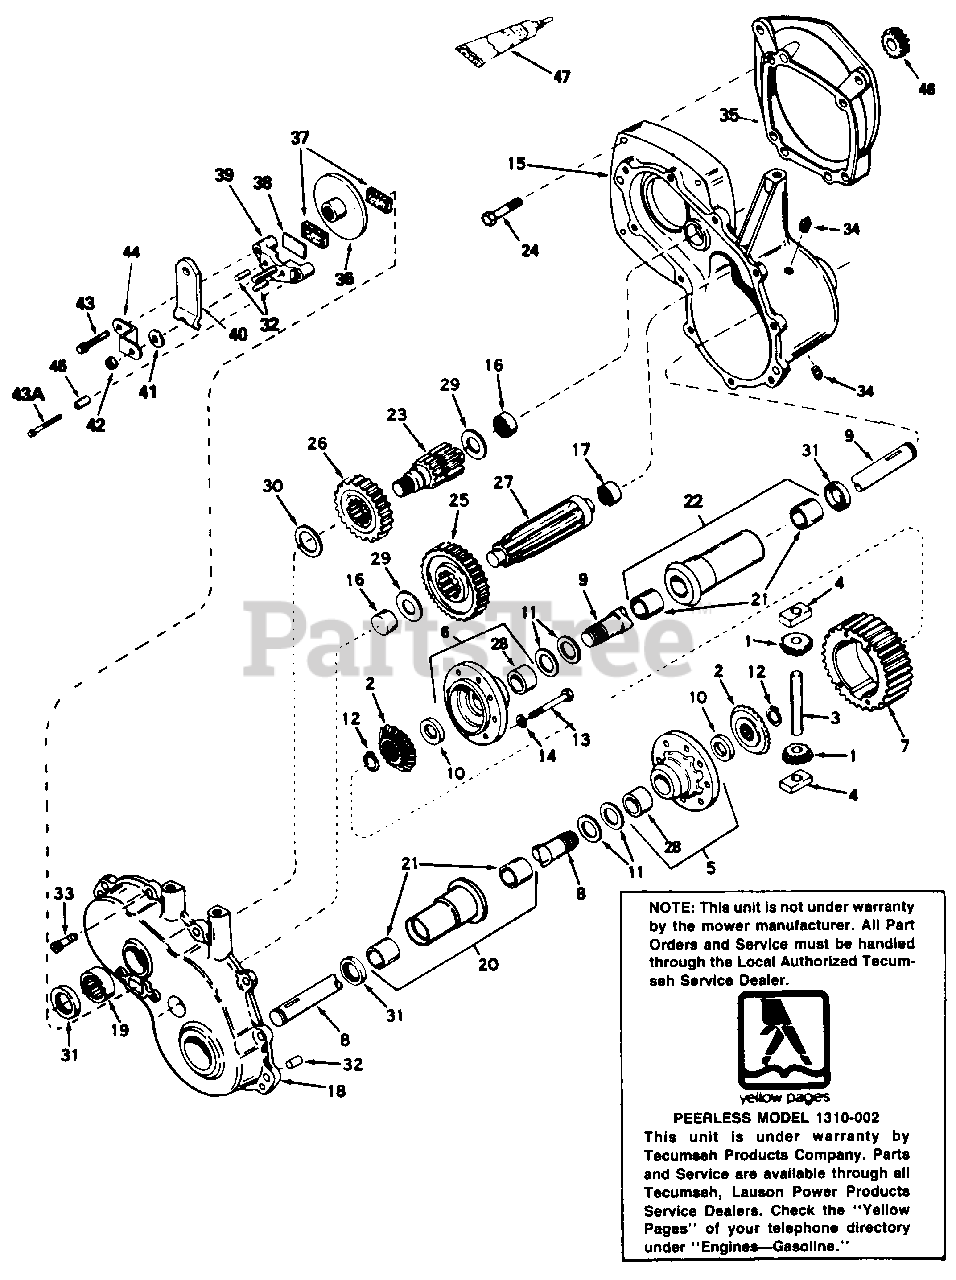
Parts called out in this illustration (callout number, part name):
1	Pinion, Bevel
2	Gear, Bevel
3	Pin, Drive
4	Block, Drive
5	Carrier Ass'y., Differential
6	Carrier Ass'y., Differential
7	Gear, Ring
8	Axie (13-1/16" Long)
9	Axle (19-1/8" Long)
10	Washer
11	Washer, Thrust
12	Ring, Snap
13	Screw, Hex Hd., 1/4-20 x 21/4
14	Lock Washer, 1/4"
15	Case Ass'y.
16	Bearing, Needle
17	Bearing, Needle
18	Cover Ass'y.
19	Bearing, Needle
20	Housing & Bushing Ass'y. (6-5/8" Long)
21	Bushing
22	Housing & Bushing Ass'y. (12-45/64" Long)
23	Shaft, Brake
24	Screw, Hex Hd., 3/8-16 x 2
25	Gear, Output
26	Gear, Idler
27	Shaft, Output
28	Bushing
29	Washer
30	Washer
31	Seal, Oil
32	Pin, Dowel
33	Screw, Hex Washer Hd. Thread Forming, 1/4-20 x 1
34	Plug, Pipe
35	Plate, Adapter
36	Disc, Brake
37	Pad, Brake
38	Plate, Brake Pad
39	Holder, Brake Pad
40	Lever, Brake
41	Washer, Flat
42	Lock Nut, 5/16-24
43	Screw, Flanged Hex Ha. Thread Forming, 1/4 20 x 1 1/4
43A	Screw, Flanged Hex Hd. Thread Forming, 1/4-20 x 21/4
44	Bracket
45	Spacer
46	Gear, Spur (18 Teeth)
47	Gasket Eliminator
